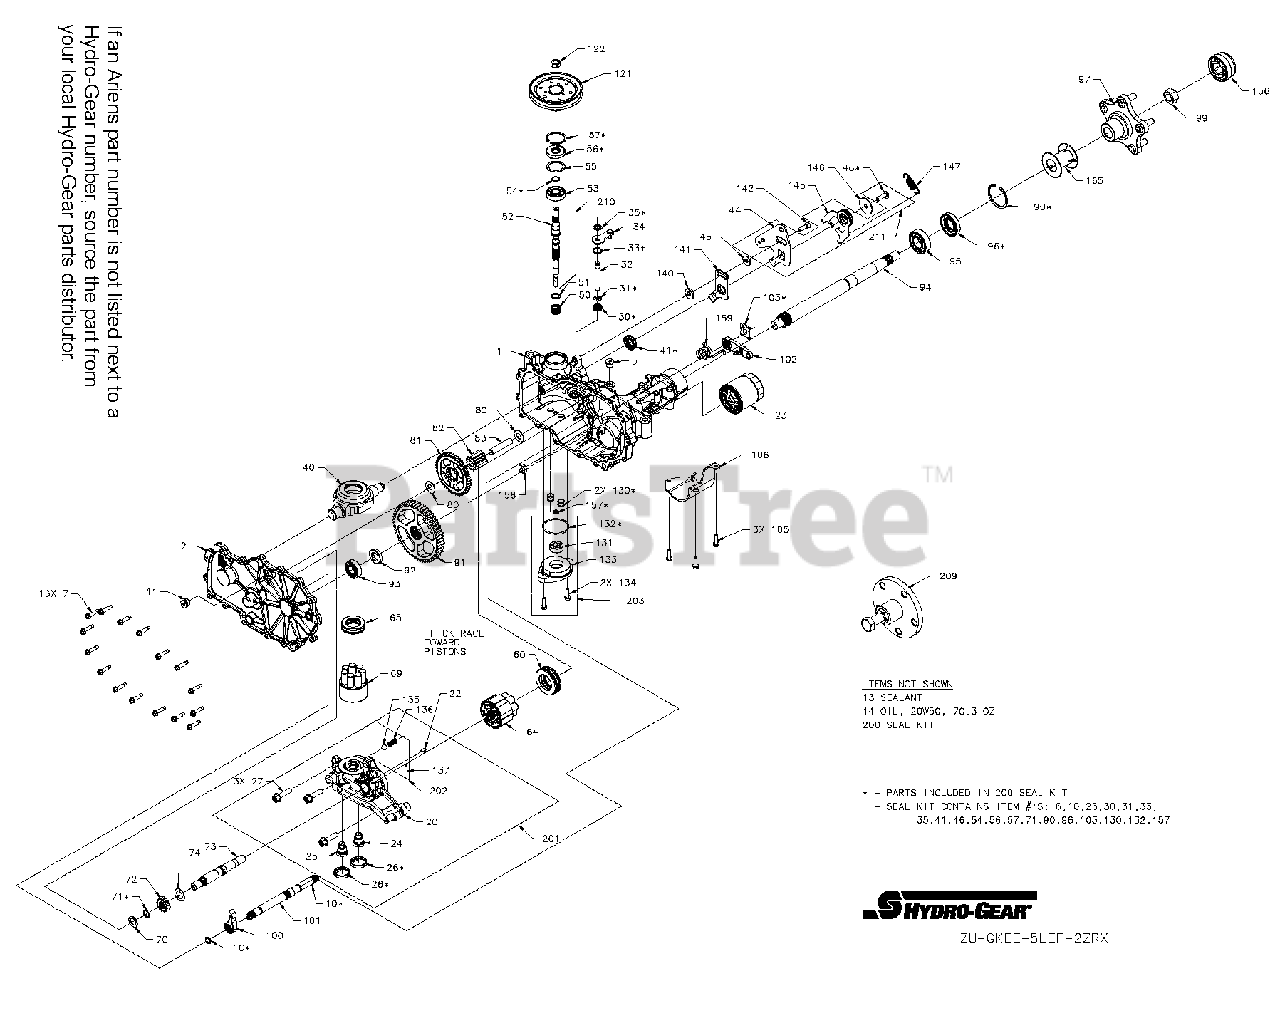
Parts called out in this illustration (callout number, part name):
13	SEALANT
23	FILTER, OIL
30	SEAL, LIP .375X.75X.25
31	RING, RET .375 EXTRNL
35	RING, RTNG .375 EXT
40	TRUNNION, SWASHPLATE
41	SEAL, LIP 12 X 32 X 7
46	TWHCS 5/16-24 X 1.00 (PATCH)
51	WASHER-FLAT .59 X .79 X .04
55	WASHER 1.23X1.56X.04
57	RING, RETAINING
80	WASHER .5X1.0X.03
95	BRG, BALL 25.4 X 52 X 15
96	SEAL, LIP 1.000 X 2.049 X .375
99	NUT, HEX LOCK 3/4-16
122	NUT,HEX JAM 1/2-20 W/ PATCH
132	O-RING, -137, 0.103 X 2.050
146	WASHER, .343 X 1.500 X .062
147	SPRING, EXTNSN RTN-34LBS
